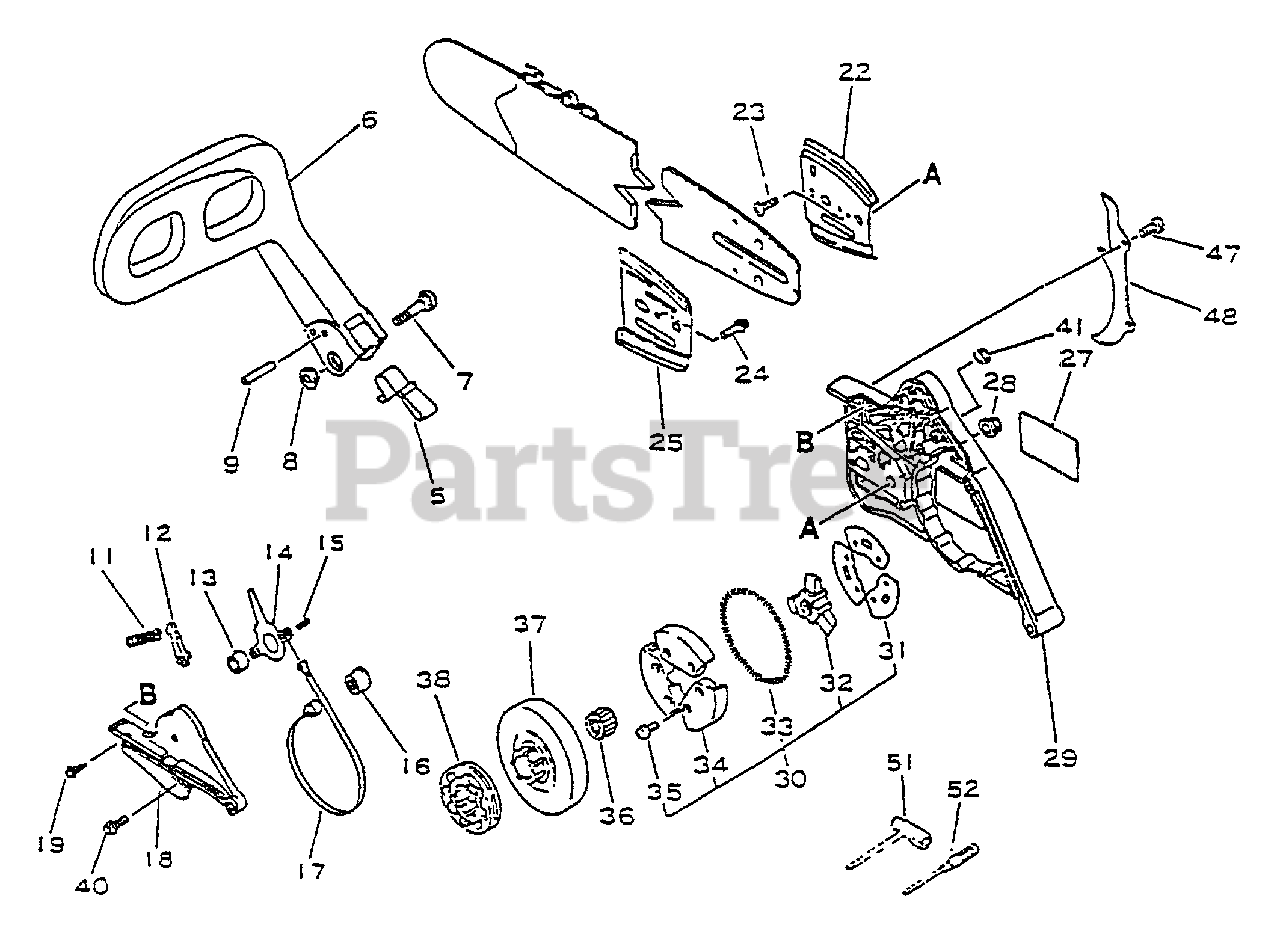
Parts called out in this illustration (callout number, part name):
5	SPRING, RETURN
6	LEVER, BRAKE
7	MOUNTING KIT
9	PIN 3.5×26
11	SPRING, BRAKE
12	STOPPER, BRAKE
13	SPACER 8×12×9
14	LEVER, BRAKE
15	PIN, SPRING - 4×8
16	ADJUSTER, BRAKE
17	BAND, BRAKE
18	COVER, BRAKE
19	SCREW 4×12
22	PLATE, GUIDE - OUTER
23	SCREW 3×6
24	SCREW 4×8
25	PLATE, GUIDE - INNER
27	LABEL, ECHO
28	NUT, FLANGE M8×1.25
29	GUARD, SPROCKET
30	CLUTCH ASSY
31	PLATE, CLUTCH
32	HUB, CLUTCH
33	SPRING, CLUTCH
34	CLUTCH SHOE SET
35	BOLT 4×6
36	BEARING, NEEDLE
37	DRUM, CLUTCH
38	SPROCKET, RIM 3/8"×7T
40	SCREW 3×18
41	NUT 3 MM
48	SPIKED BUMPER KIT
51	T-WRENCH 13×19×180
52	SCREWDRIVER, PHILLIPS
